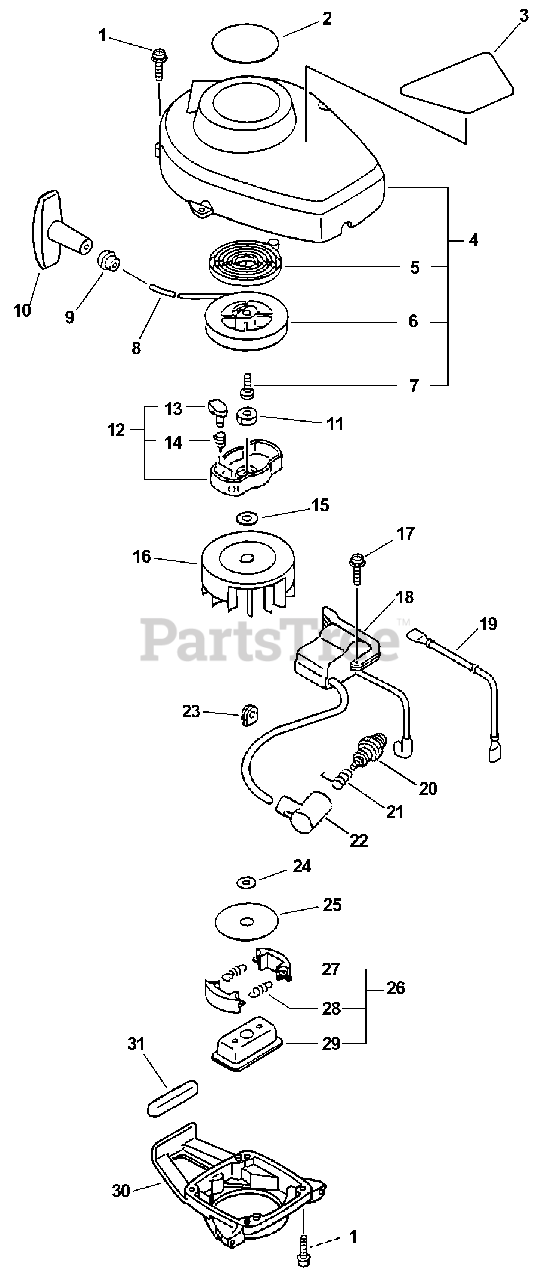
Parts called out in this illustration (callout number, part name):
1	BOLT 4×16
2	LABEL, HC-2400
2	LABEL, HC-2410
3	LABEL, CAUTION
3	LABEL, CAUTION - ISO
4	STARTER ASSY
5	SPRING, RECOIL
6	REEL, ROPE
7	SCREW
8	ROPE, STARTER
9	GUIDE, ROPE
10	GRIP, STARTER
12	STARTER PAWL ASSY
13	PAWL, STARTER - BLACK
14	SPRING, RETURN
15	WASHER 8.5×16×1.2
16	FLYWHEEL
17	SCREW 4×22
18	COIL, IGNITION
19	LEAD - GROUND
20	SPARK PLUG - BPM-7Y
20	SPARK PLUG - RCJ7Y
21	TERMINAL, SPARK PLUG
22	CAP, SPARK PLUG
24	WASHER, CLUTCH
25	PLATE, CLUTCH
26	CLUTCH ASSY
27	SHOE, CLUTCH
28	SPRING, CLUTCH
29	HUB, CLUTCH
30	CASE, CLUTCH
31	CUSHION, FUEL TANK
